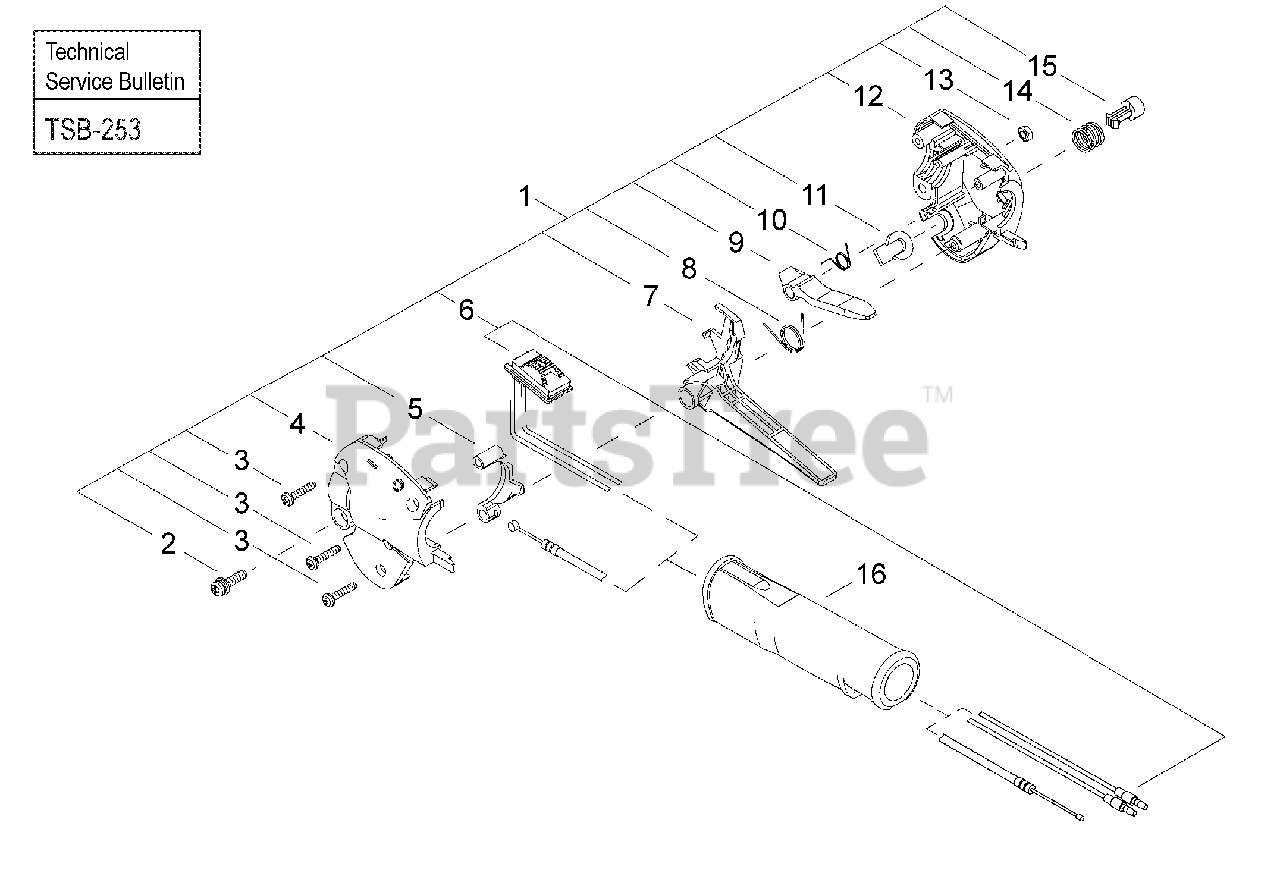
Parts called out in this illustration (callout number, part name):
1	THROTTLE CONTROL ASSY
2	SCREW - 5X20
3	SCREW - 4X20 -- TAPPING
4	HANDLE, CONTROL - LEFT
5	LOCKOUT, THROTTLE
6	SWITCH, IGNITION
7	TRIGGER, THROTTLE
8	SPRING
9	LEVER, TRIGGER LOCKOUT
10	SPRING
11	PLUG
12	HANDLE, CONTROL - RIGHT
13	NUT - 5
14	SPRING
15	BUTTON, THROTTLE LOCK
16	GRIP - REAR
